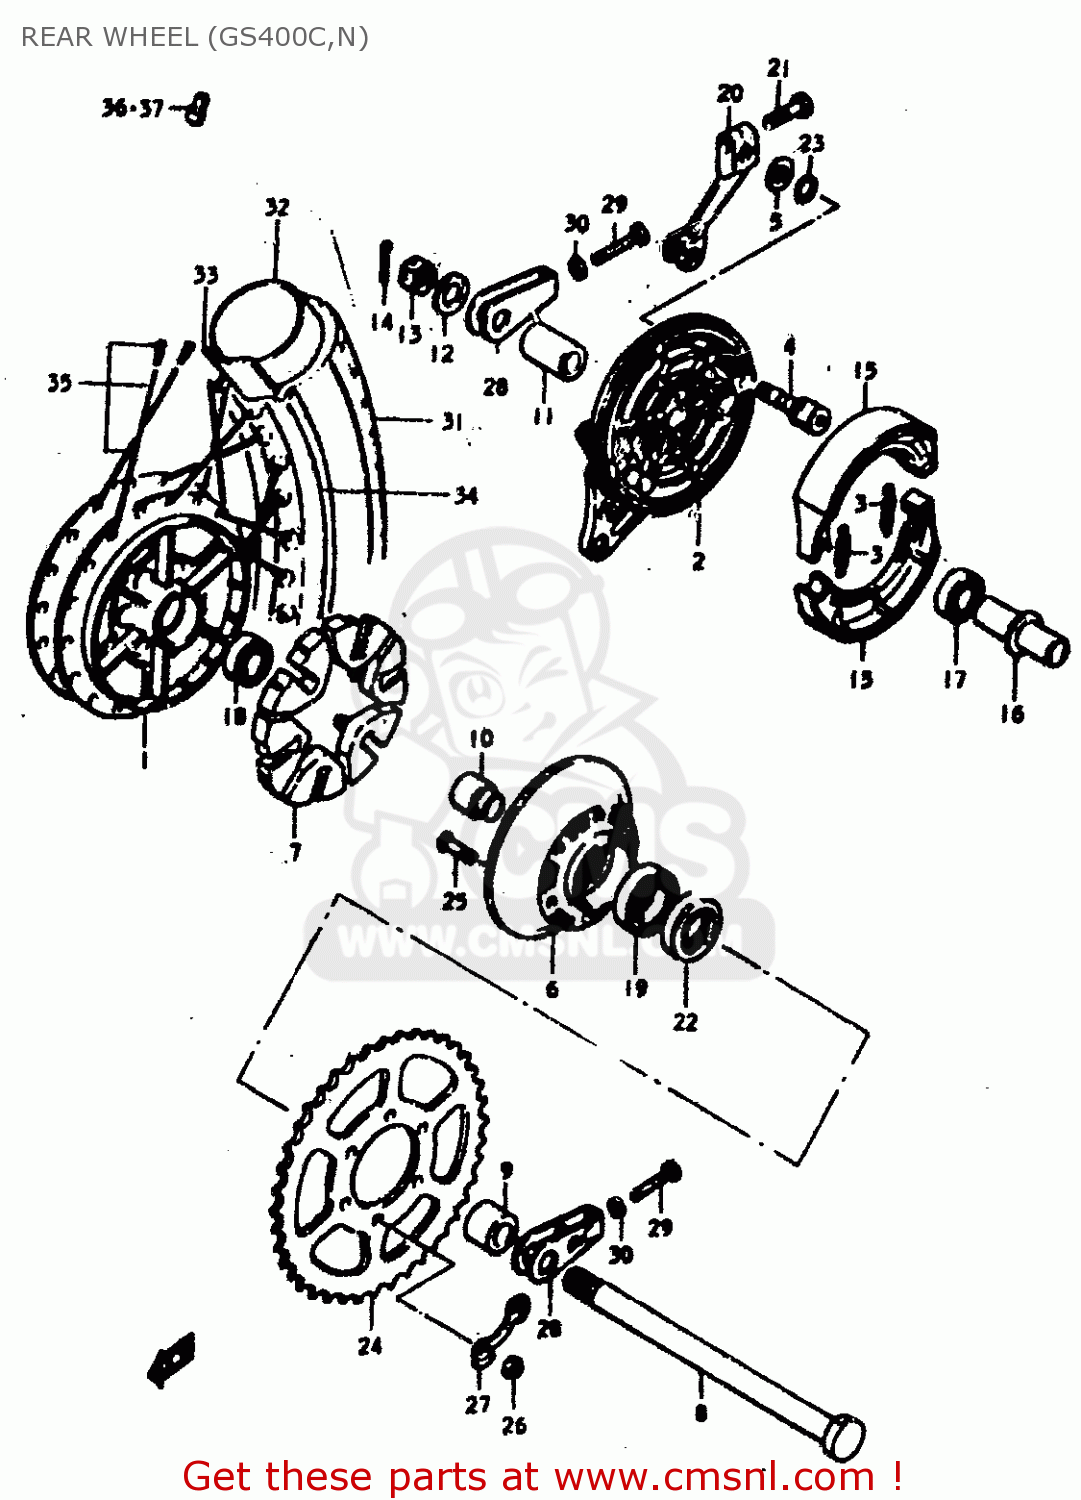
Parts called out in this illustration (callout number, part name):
1	DRUM,REAR HUB
2	PANEL,REAR HUB
3	SPRING,BRAKE SHOE
4	CAM,FRONT BRAKE
5	WASHER (15X24X1.6)
6	DRUM,REAR SPROCKET MOUNT
7	CUSHION,REAR DRUM
8	AXLE,REAR
9	SPACER(17.5X28X44.8)
10	SPACER,REAR HUB BEARING
11	SPACER(17X30.5X22.3)
12	WASHER (17X30X3.2)
13	NUT
14	PIN,COTTER
15	SHOE SET,BRAKE (MCA)
16	SPACER
17	BEARING
18	BEARING
19	BEARING
20	LEVER,REAR BRAKE CAM
21	BOLT
22	OIL SEAL
23	O-RING,BOSS
24	SPROCKET,RR
25	BOLT
26	NUT
27	WASHER
28	ADJUSTER,CHAIN
29	BOLT
30	NUT
31	TIRE
32	TUBE ASSEMBLY,WHEEL,INNER
33	PROTECTOR,INNER TUBE
34	RIM,RR WHEEL
35	SPOKE SET,REAR WHEEL
36	BALANCER,WHEEL (B)
37	BALANCER,WHEEL (30G)
